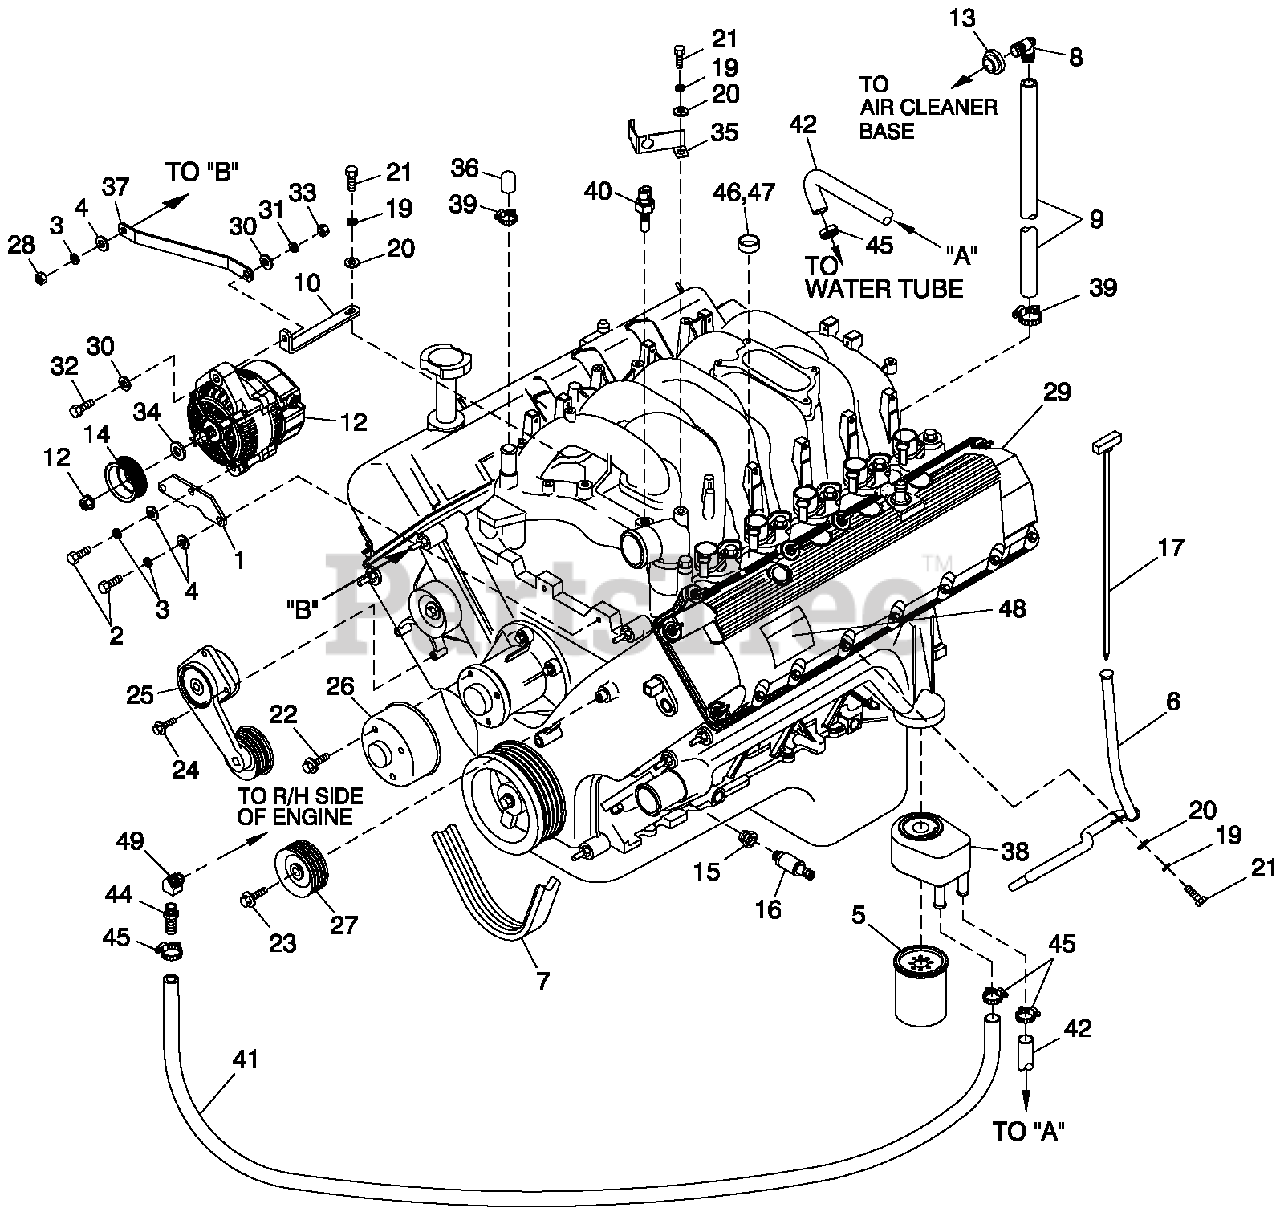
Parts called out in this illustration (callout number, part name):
1	BRACKET,D.C. ALTERNATOR LOWER
2	SCREW HHC M8-1.25X20 G8.8
3	WASHER LOCK M8-5/16
4	WASHER FLAT 5/16-M8 ZINC
5	OIL FILTER, FORD V-10 ENGINE
6	DIPSTICK TUBE, FORD 6.8L
7	BELT SERPENTINE (65.0" LG) (1800 RPM)
8	BARBED EL 90 3/4 PLASTIC
9	HOSE 3/4 ID SAE-30R2 (16.75" LG)
10	BRACKET DC ALTERNATOR UPPER
12	ALTERNATOR DC W/OUT PULLEY
13	GROMMET
14	PULLEY 80 OD DC ALTERNATOR (1800 RPM)
15	BSHG RDCRHEX1/4 TO 1/8
16	SENDER OIL PRESSURE 1/8" NPT
17	DIPSTICK 6.8L FORD
18	TIE WRAP UL 7.4" X .19" BLK
19	WASHER LOCK M6-1/4
20	WASHER FLAT 1/4 ZINC
21	SCREW HHC M6-1.0 X 20 G8.8
22	BOLT WATER PUMP PULLEY
23	BOLT GROOVED IDLER PULLEY
24	BOLT BELT TENSIONER
25	TENSIONER ENG. AUTOMATIC BELT
26	PULLEY WATER PUMP FORD (1800RPM UNITS)
27	PULLEY GROOVED ENGINE IDLER
28	NUT HEX M8-1.25 G8 YEL CHR
29	ENGINE G6.8L G3V-10
30	WASHER FLAT 3/8-M10 ZINC
31	WASHER LOCK M10
32	SCREW HHC M10-1.5 X 45 G8.8 FT
33	NUT HEX M10-1.5 G8 YEL CHR
34	SPACER DC ALTERNATOR PULLEY
35	BRACKET SIGNAL CONDITIONER
36	CAP RUBBER
37	BRACKET DC ALT STABILIZER
38	OIL COOLER FORD (150KW 3600RPM)
39	CLAMP HOSE #10 .56-1.06
40	TEMPERATURE SENDER DELPHI
41	HOSE OIL COOLER PREFORMED 3/4 (150KW 3600RPM)
42	HOSE OIL COOLER (150KW 3600RPM)
44	BARBED STR 1/2NPT X 3/4
45	CLAMP HOSE #10 .56-1.06 (150KW 3600RPM)
46	PLUG EXPANSION 14 OD
47	ADHESIVE LOCTITE 620
48	DECAL EMISSION CTRL INFO 6.8L
49	ELBOW 45D STREET 1/2NPT BRASS
